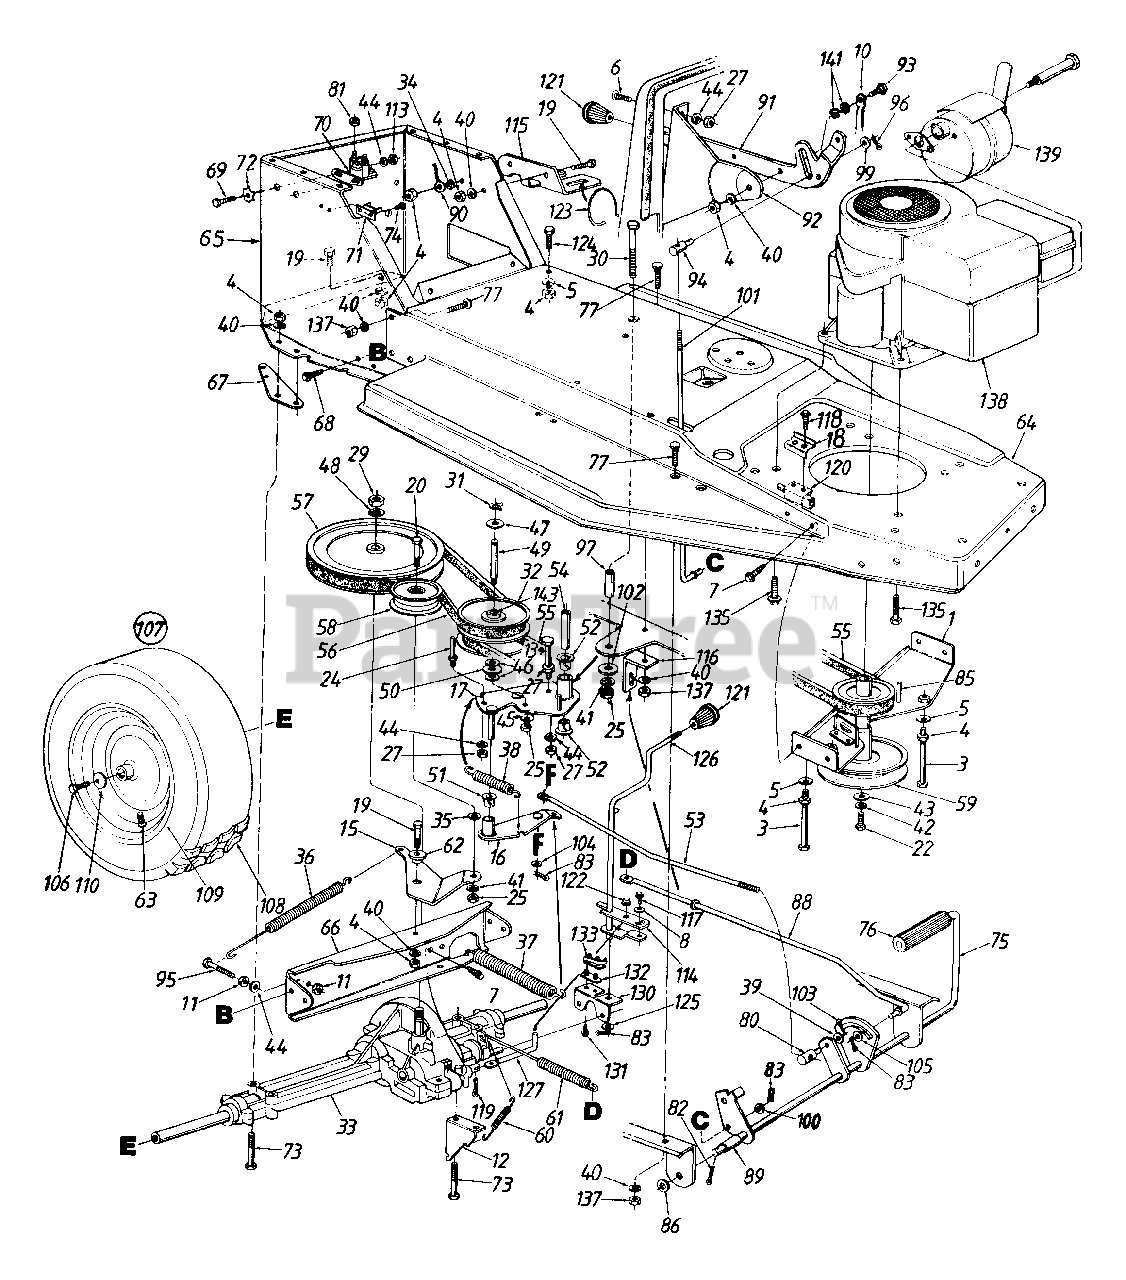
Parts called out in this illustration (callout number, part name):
1	Engine Pulley Belt Guard Ass'y.
3	Hex Bolt 5/16-18 x 51/4" Lg.
4	Hex Nut 5/16-18 Thd.
5	Bell-Wash..345" I.D. x .88
6	Truss-Mach. Scr. 1/4-20 x 50" Lg.
7	Hex TT-Tap Scr. 1/4 x .5" Lg.
8	Bell-Wash..265" I.D. x .75
10	Speed Selector Brace
11	Hex Nut 1/4-28 Thd.
13	Hex Bolt 1/4-20 x 3.5" Lg.
17	Variable Speed Brkt. Ass'y.
18	Switch Plate
19	Hex Bolt 5/16-18 x .75" Lg.
20	Hex Bolt 3/8-24 x 2.0" Lg. Gr. 5
22	Hex Bolt 7/16-20 x 1.5" Lg.
24	Belt Guard Pin
25	Hex Nut 3/8-24 Thd.
27	Hex Nut 1/4-20 Thd.
29	Hex Jam Nut 9/16-18 Thd.
30	Hex Bolt 3/8-24 x 4.0" Lg.
31	Snap Ring
32	Variable Speed Pulley Ass'y.
33	Transaxle Complete (See Breakdowns)
34	Ext. L-Wash. 5/16" I.D.
35	Fl-Wash. 3/8" I.D. x 1.0" O.D.
36	Extension Spring 6.12" Lg.
37	Extension Spring 7.58" Lg.
38	Extension Spring 2.59" Lg.
39	Fl-Wash..385" I.D. x .620"
40	L-Wash. 5/16" I.D.
41	L-Wash. 3/8" I.D.
42	L-Wash. 7/16" I.D.
43	Fl-Wash..450" I.D. x 1.25"
44	L-Wash. 1/4" I.D.
45	Bell-Wash..39" I.D. x 1.13"
46	Fl-Wash..56" I.D. x 1.0" O.D.
47	Washer "Teflon" .565 I.D.
48	Bell-Wash..56" I.D. x 1.125"
49	Shaft .56" Dia. x 3.875" Lg.
50	Thrust Brg. 1.25 O.D.
51	Flanged Nyliner Brg.
52	Nyliner Flanged Brg.
53	Speed Control Rod
54	Spacer
55	V-Belt
56	V-Belt
57	V-Pulley
58	Idler Pulley 3-1/8" Dia.
59	Dbl. Pulley 6.0" Dia. x 3.56"
60	Extension Spring 3.18" Lg.
61	Extension Spring 7.08" Lg.
62	Shld. Spacer .500" Dia.
63	Air Valve
69	Hex Bolt 1/4-20 x .62" Lg.
70	Solenoid
71	Circuit Breaker
72	Ext. L-Wash. 1/4" I.D.
73	Hex Bolt 5/16-18 x 2.75" Lg.
74	Truss Mach. B-Tap Scr. #10 x .50" Lg.
75	Foot Pedal Rod Ass'y.
76	Foot Pad
77	Ribbed Neck Bolt 5/16-24 x 84" Lg
80	Ferrule
81	Hex Sems Nut 1/4-20 Thd.
82	Cot-Pin 1/8" Dia. x 1.25" Lg.
83	Cot-Pin 3/32" Dia. x .75" Lg.
85	Sq. Key 1/4 x 2.0" Lg.
86	Fl-Wash..635" I.D. x 1.0"
88	Brake Rod
89	Spacer 5/8" I.D. x 1.2" Lg.
90	Ground Wire 7.25" Lg.
91	Speed Selector Lever
92	5 Speed Selector Brkt.
93	Shld. Bolt .437" Dia. x .47" Lg.
94	Ferrule
95	Hex Bolt 1/4-28 x 1.25" Lg.
96	Intern. Cot-Pin 5/16" Dia.
97	Spacer .375" I.D. x .625"
99	Fl-Wash..344" I.D. x .62"
100	Fl-Wash..25" I.D. x .62" O.D.
101	Speed Control Rod
102	Fl-Wash. 3/8" I.D. x .1.25" O.D.
103	Cot-Pin 1/8" Dia. x 1.0" Lg.
104	Fl-Wash..34" I.D. x .68" O.D.
105	Fl-Wash..34" I.D.
106	Hex L-Bolt 5/16-24 x .75" Lg.
107	Rear Wheel Ass'y. Comp.
110	Bell-Wash..345" I.D. x .88"
113	Hex Jam Nut 1/4-20 Thd.
114	Shift Lever Adjusting Link
115	Speed Control Rod Brkt.
118	Hex B-Tap Scr. #10 x .38" Lg.
119	Intern. Cotter Pin
120	Safety Switch (Clutch)
121	Knob
122	Retaining Ring
123	Compression Spring Clip
124	Hex Wash. Hd. Scr. 5/16-18 x 62" Lg.
125	Fl-Wash..469" I.D. x .88"
130	Shift Lever Support
131	Hex Wash. Hd. #8 x .50" Lg.
132	Insulator Nut Plate
133	Spring Switch
135	Hex L-Wash. TT-Tap Scr. 3/8-16 x 1.25" Lg.
137	Hex Nut 5/16-24 Thd.
138	Engine
139	Muffler
141	Wave Wash..445" I.D.
143	Needle Brg.
